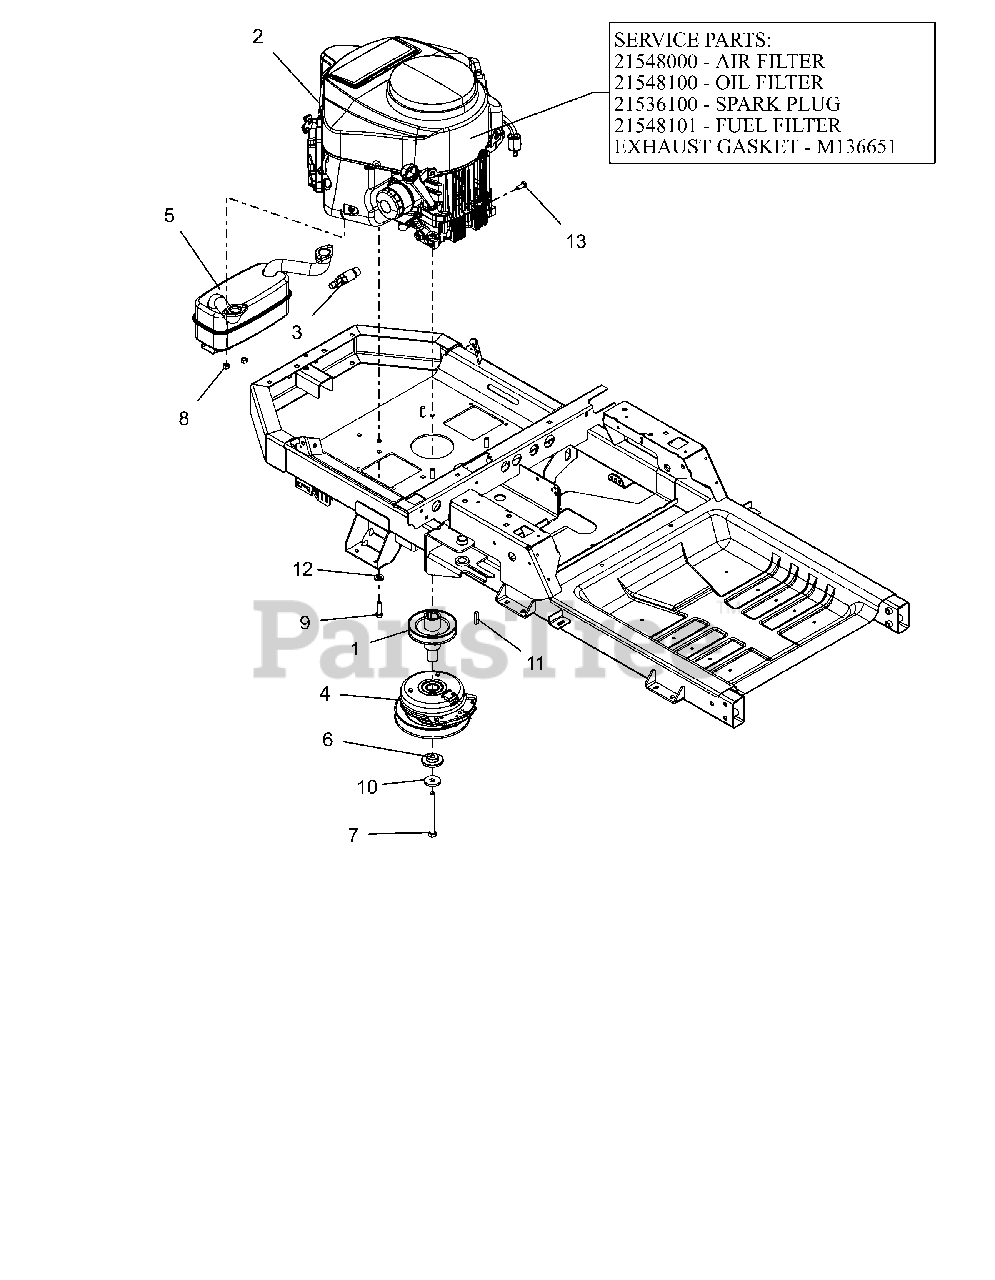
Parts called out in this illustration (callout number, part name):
1	WLDMT, DRIVE SHEAVE-X
2	ENGINE, KAWASAKI FR691 23HP
2	AIR FILTER, KAWASAKI FR
2	OIL FILTER, KAWASAKI FR
2	PLUG, SPARK
2	FUEL FILTER-KAWASAKI FR
2	GASKET, MUFFLER #
3	DRAIN, OIL M20X2.5
4	CLUTCH,105FTLB MONOPOLE 6.83"
5	MUFFLER, KAWASAKI
6	BSHG-FLG .469X1.06X.574X2.0
7	BLT-HEX.438-20X4.5GR8YZ NYTORQ
8	NUT-LK-TOP M8-1.25 YWZC
9	BLT-HEX.38-16X1.25 G5YZ NYTORQ
10	WASHER, 7/16" SPRING DISK
11	KEY-SQ .25 X 1.25 X .25 SAE
12	WASHER, 3/8" SPRING DISC
13	BLT, HEX M8-1.25X20 G8.8 ZCC
